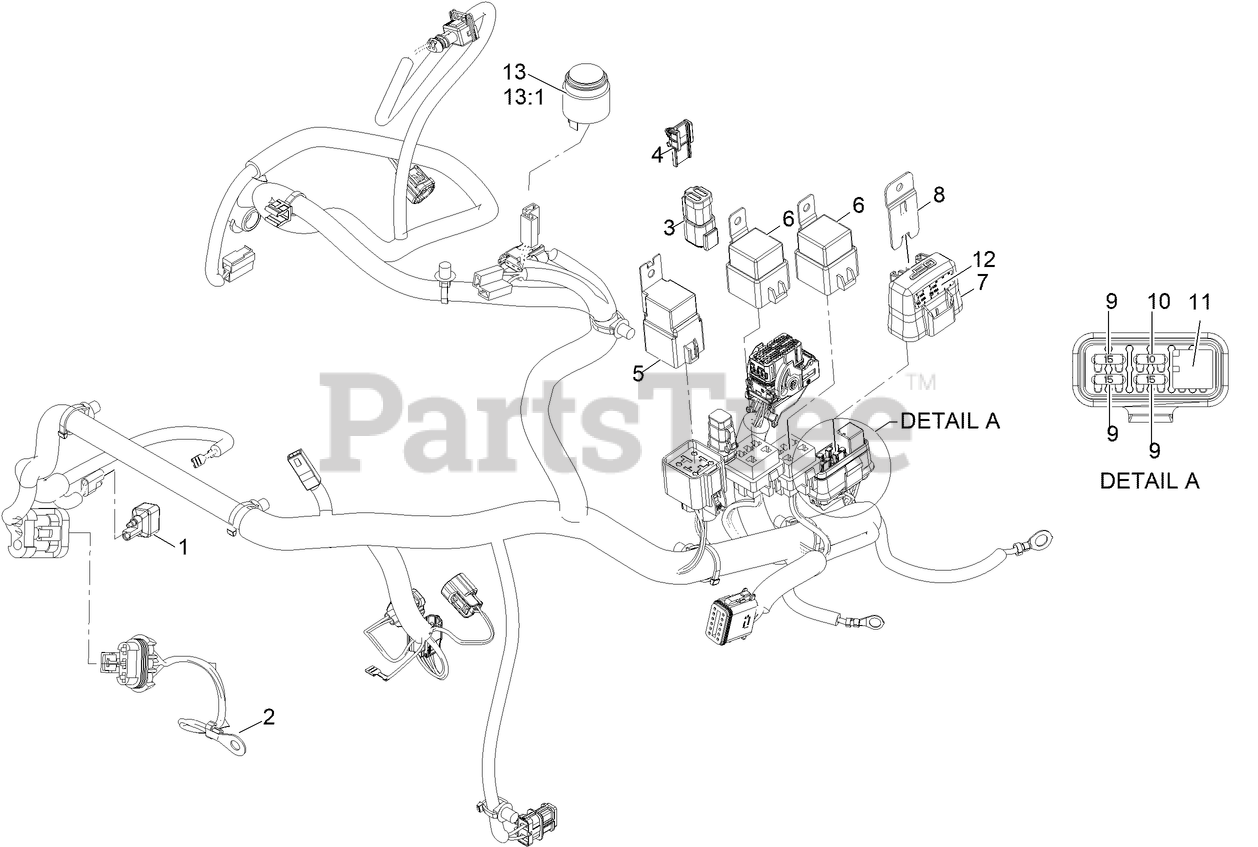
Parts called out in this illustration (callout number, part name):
2	HARNESS-WIRE, FUSIBLE LIN
3	Connector (6M)
4	CLIP-CONNECTOR
5	RELAY-70A
6	RELAY-MINI
7	COVER-BLOCK, FUSE
8	CLIP-MOUNTING
9	FUSE-MINI BLADE, 15 AMP
10	FUSE-MINI BLADE, 10 AMP
11	RELAY-MICRO
12	DECAL-FUSE
13	Audio Alarm ASM
13:1	Nut-Plastic, Knurled
